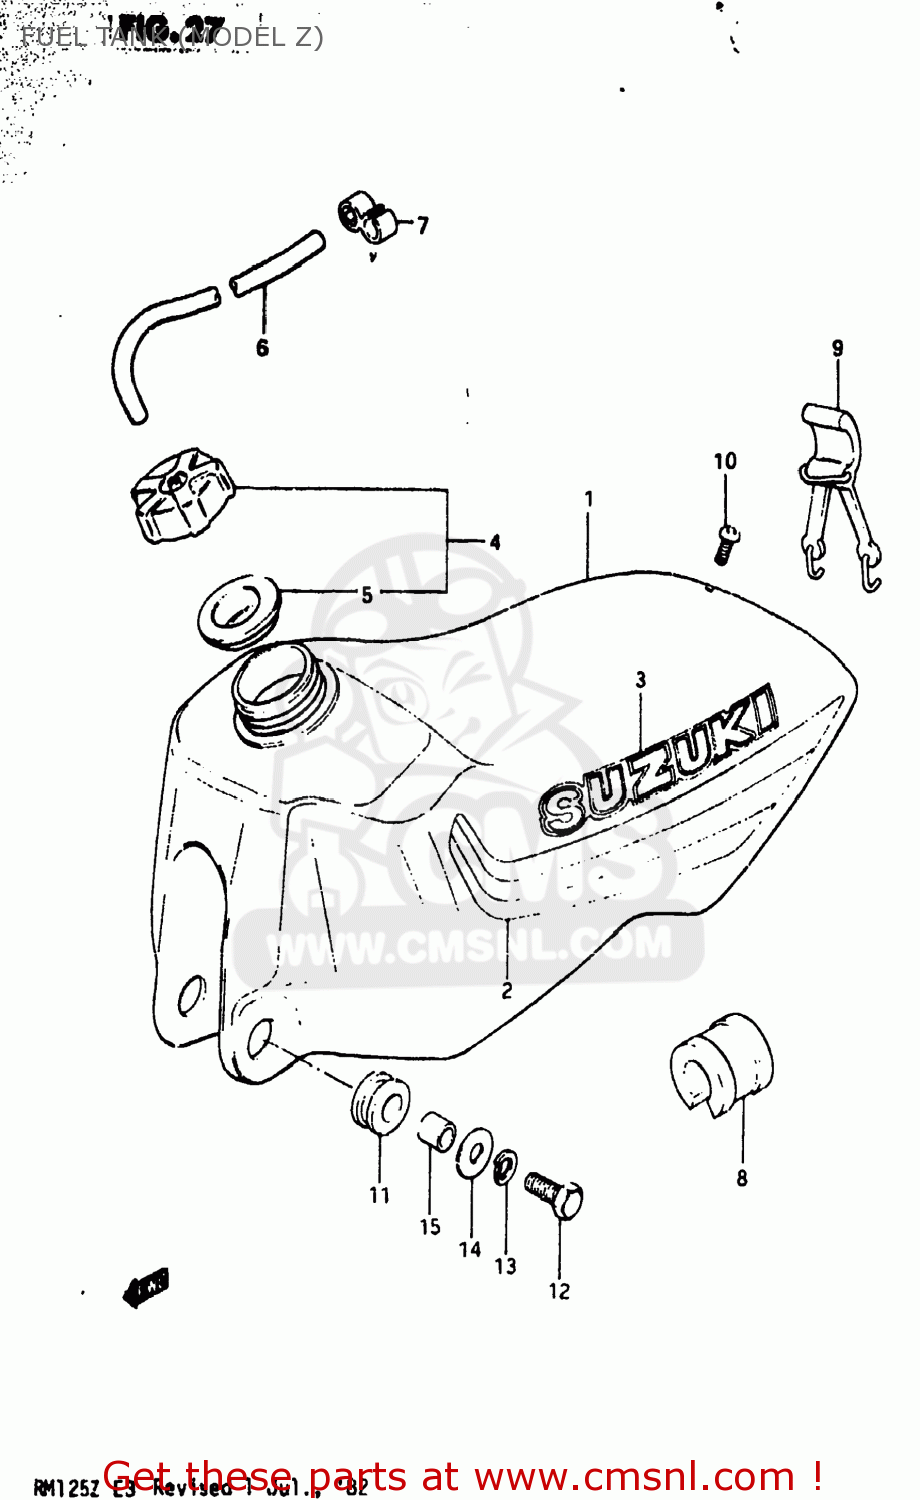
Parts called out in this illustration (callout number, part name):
1	TANK ASSEMBLY,FUEL
2	TAPE SET,FUEL TANK
3	EMBLEM
4	CAP SET,FUEL TANK
5	GASKET,FUEL TANK CAP (NAS)
6	HOSE
7	CLAMP,BREATHER HOSE
8	CUSHION,FUEL TANK UPR
9	BAND,FUEL TANK,REAR
10	SCREW (6X15)
11	CUSHION
12	BOLT
13	LOCK WASHER
14	WASHER
15	SPACER (8.8X12X13.5)
